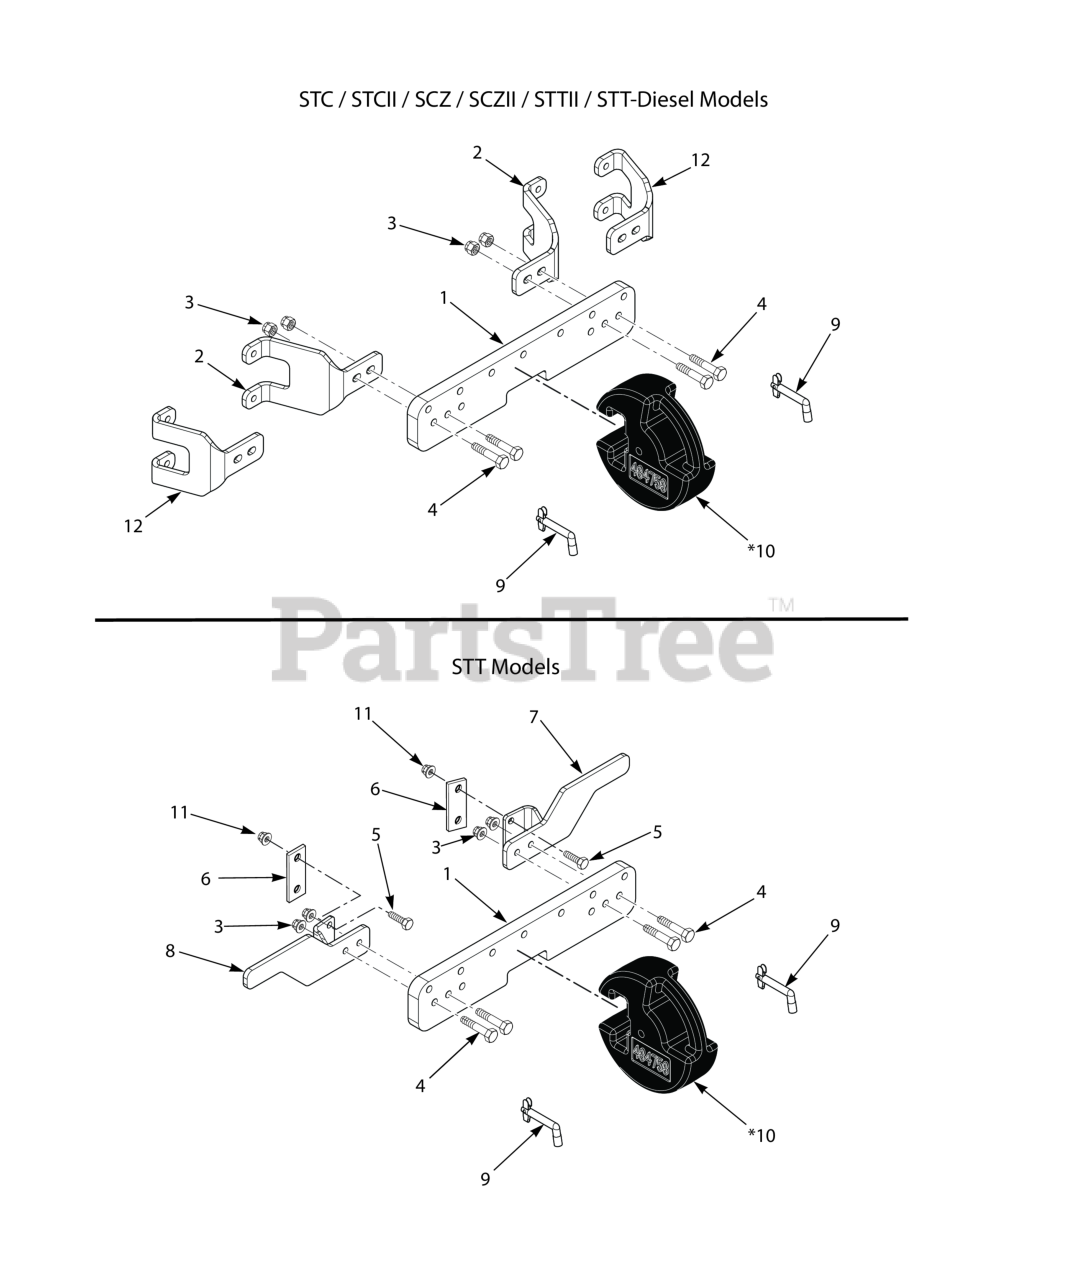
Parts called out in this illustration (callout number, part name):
1	Weight Bar
2	Bracket, LH Weight Bar (STC / STCII & SCZ48/52)
3	Nut, Elastic Stop 1/2-13, (STT-52 & STTII-52)
4	HEX HD. BOLT 1/2-20 X 2 SPECIAL
5	Bolt, Hex Head 3/8-16 x 1-1/2" B&S 32BV
6	Clamp, Bar
7	Mounting Bracket Weldment, LH Weight Bar
8	Mounting Bracket Weldment, RH Weight Bar
9	Pin, Weight Retention
10	Weight
11	Nut, Flange Elastic Stop Nut, 3/8-16
12	BRKT, WEIGHT BAR
